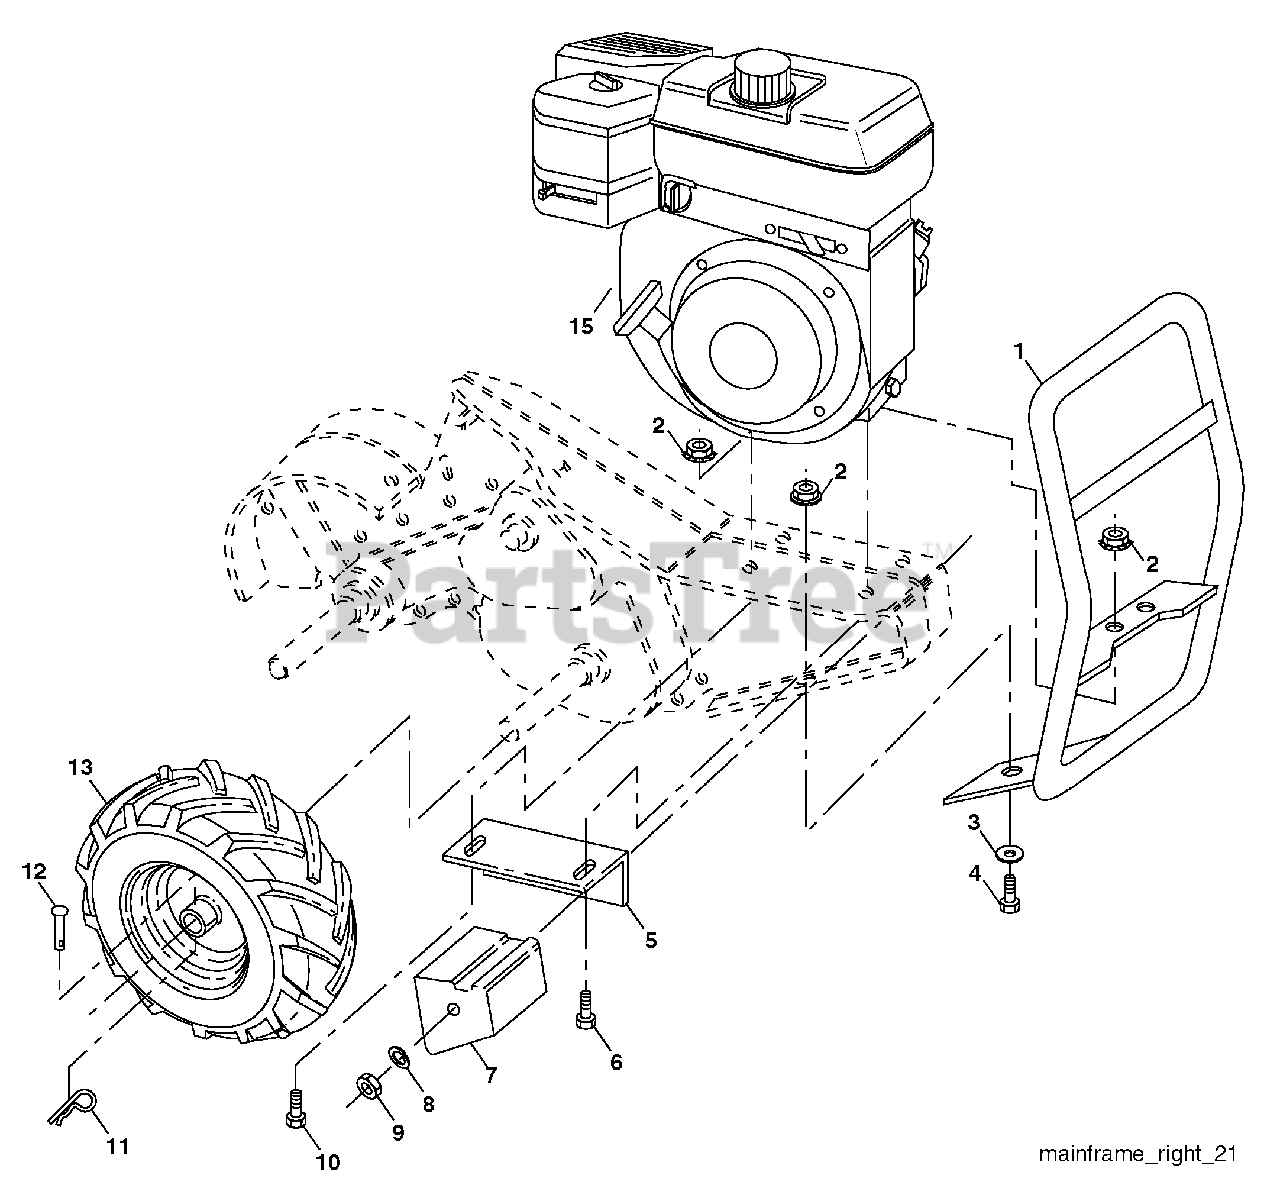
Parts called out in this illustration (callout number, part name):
2	Locknut, Hex, Flange 5/16-18
3	Washer 11/32 x 11/16 x 16 Ga.
4	Bolt, Hex 5/16-18 x 3/4
5	Bracket, Reinforcement
6	Bolt, Hex 5/16-18 x 1-3/4
7	Counter Weight, R.H.
8	Washer, Lock 3/8
9	Nut, Hex 3/8-16
10	Bolt, Hex 5/16-18 x 1-1/2
11	Clip, Hairpin
12	Rivet, Drilled
13	Tire
13	Rim
13	Tire Valve
